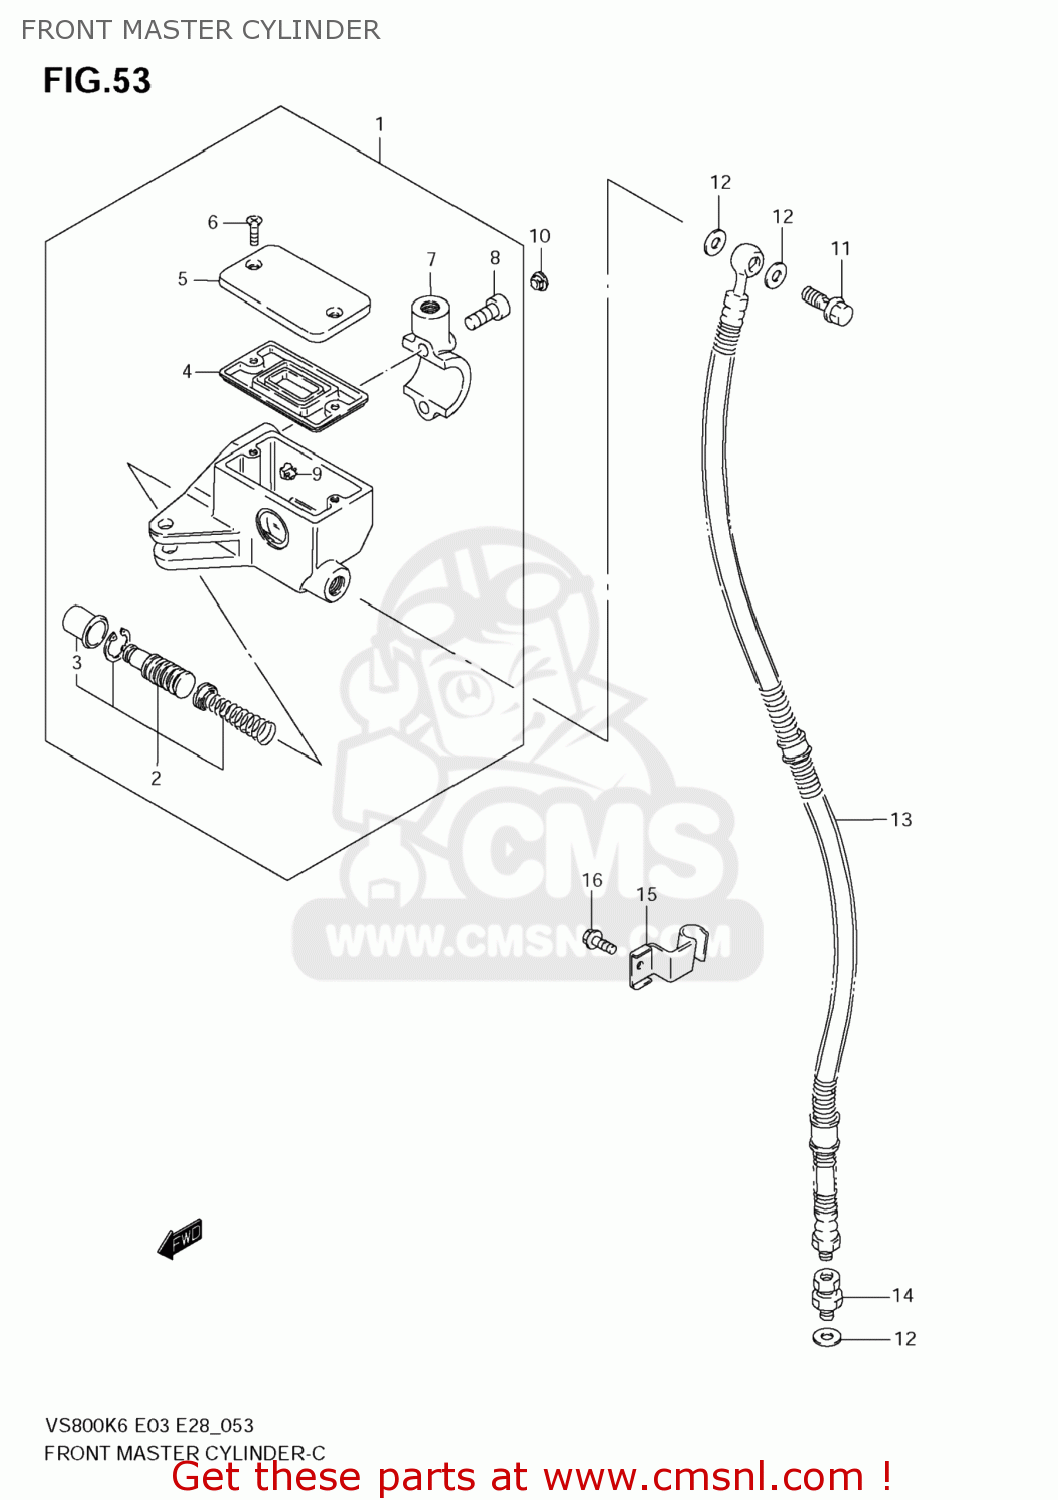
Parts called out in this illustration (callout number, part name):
1	CYLINDER ASSY,FR MASTER
2	PISTON/CUP SET
3	BOOT
4	5
5	CAP
6	SCREW
7	HOLDER
8	BOLT
9	PROTECTOR
10	CAP(OD:10)
11	BOLT UNION
12	WASHER(10X15X1.5)
13	HOSE,FR BRAKE
14	ADAPTER,BRAKE HOSE
15	GUIDE,BRAKE HOSE
16	BOLT
